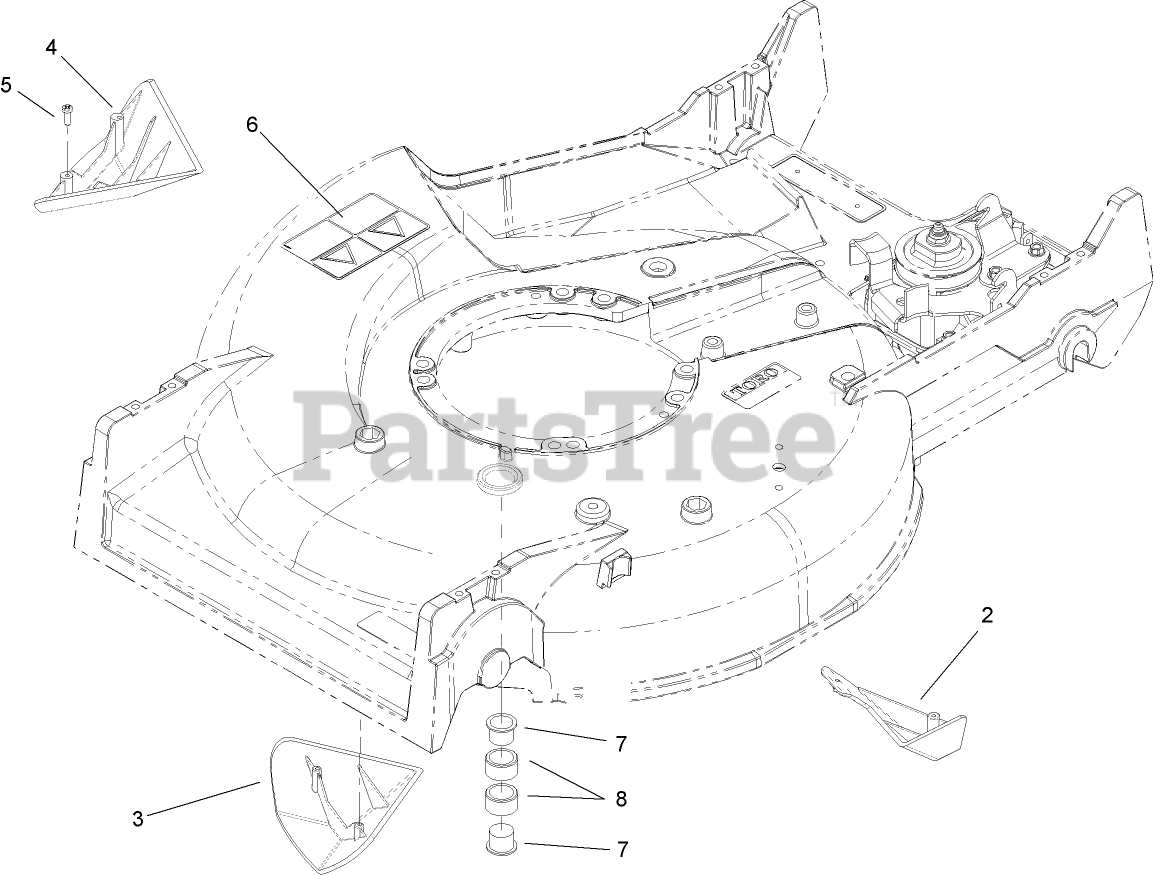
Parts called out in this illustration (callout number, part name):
2	KICKER-REAR
3	KICKER-FRONT
4	KICKER-RH
5	SCREW-PPH
6	DECAL-DANGER
7	CAPLUG (L-9)
8	BEARING
